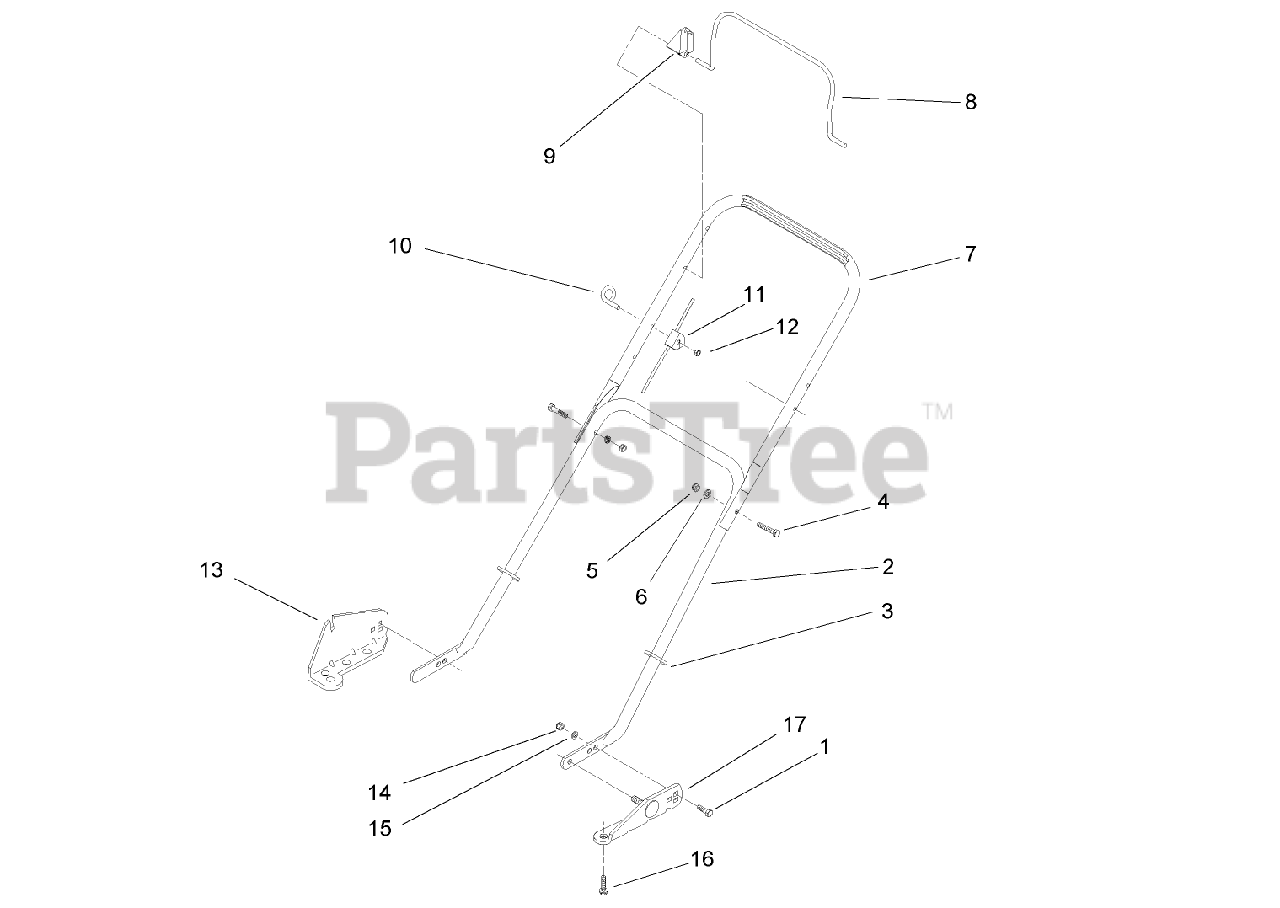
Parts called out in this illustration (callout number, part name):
1	SCREW-CARR
2	HANDLE-SECTION, LOWER
3	TIE-CABLE
4	SCREW-HH
5	NUT-LOCK, NI
6	WASHER-CURVED
7	HANDLE-UPPER
8	BAIL CONTROL LEVER ASM
9	STOP-PIVOT
10	GUIDE-ROPE
11	BRAKE CABLE ASM
12	NUT-LOCK, NI
13	RH BRACKET and PIN ASM
14	NUT-LOCK, NI
15	WASHER-PLAIN
16	SCREW
17	LH BRACKET and PIN ASM
